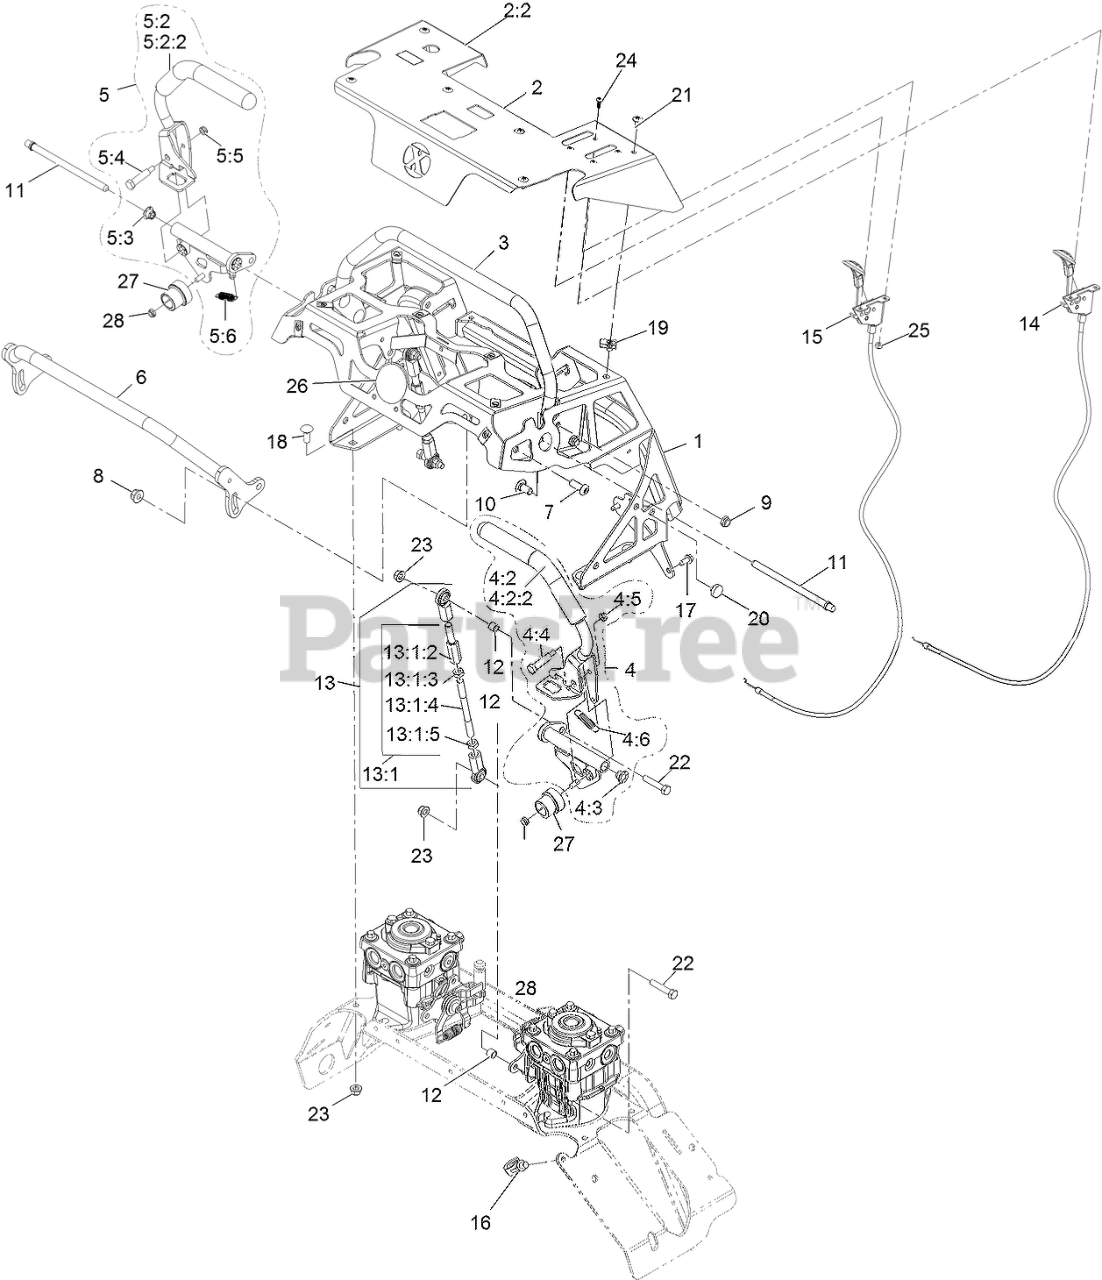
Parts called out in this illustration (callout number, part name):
1	ASM, Control Tower W/Decal
2	ASM,Control Panel W/Decal
2:2	Decal-Control Panel Non-EFI
3	Weld, Rear Ref Bar
4	ASM, Motion Control, Lt
4:2	ASM, Lt Control Lever W/ Grip
4:2:2	Grip, Drive Lever
4:3	Bearing, Igus
4:4	BOLT-SHOULDER
4:5	NUT-LOCK, NI
4:6	SPRING-EXTENSION
5	ASM, Motion Control, Rt
5:2	ASM, Rt Control Lever W/ Grip
5:2:2	Grip, Drive Lever
5:3	Bearing, Igus
5:4	BOLT-SHOULDER
5:5	NUT-LOCK, NI
5:6	SPRING-EXTENSION
6	Weld, Front Ref Bar
7	SCREW-HSBH
8	NUT-HF, NI
10	SCREW-CARR
11	PIN, PIVOT
13	ASM, Linkage
13:1	ASM, Motion Control Link
13:1:2	ROD-ADJUSTMENT
13:1:3	NUT-HEX JAM, LH
13:1:4	Link, Motion Control
13:1:5	NUT-HJ
14	CONTROL, CHOKE
15	CONTROL, THROTTLE
16	CLIP-TIE
17	SCREW-HWH
18	SCREW-CARR
21	SCREW-TORX
22	SCREW-HH
23	NUT-HF, NI
24	SCREW, BHCS
25	NUT-LOCK, NI
26	Decal-Cover
28	NUT-LOCK, NI
